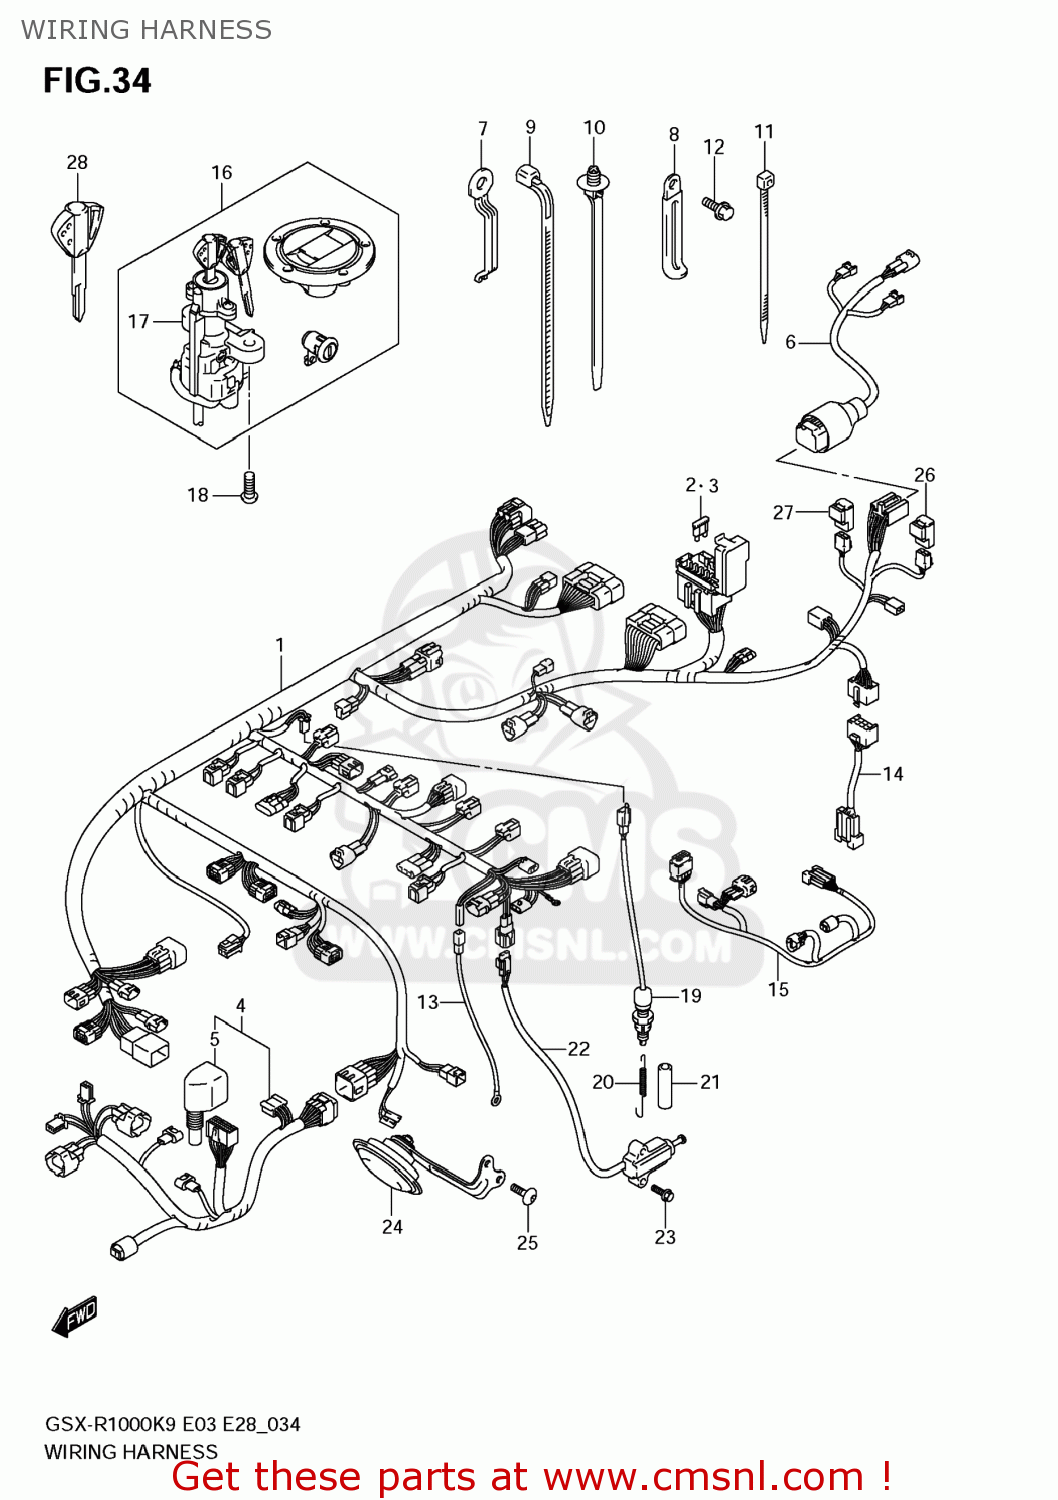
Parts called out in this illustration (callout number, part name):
1	HARNESS,WIRING
2	FUSE(10A)
3	FUSE(15A)
4	HARNESS,WIRING NO.2
5	COVER,CONNECTOR
6	WIRE,RR COMB
7	CLAMP
8	CLAMP(L:45)
9	CLAMP(L:125)
10	CLAMP(L:154)
11	CLAMP(L:145)
12	BOLT
13	WIRE,OIL PRESSURE SWITCH LEAD
14	WIRE,RELAY LEAD
15	WIRE,ISC LEAD
16	LOCK SET
17	LOCK ASSY,STEERING
18	BOLT(8X20)
19	SWITCH ASSY,STOP LAMP
20	SPRING
21	HOSE(5X8.2X600)
22	SWITCH ASSY,SIDE STAND
23	BOLT
24	HORN ASSY
25	SCREW(6X16)
26	RELAY ASSY
27	RELAY ASSY
28	KEY,BLANK(IMMOBII)
